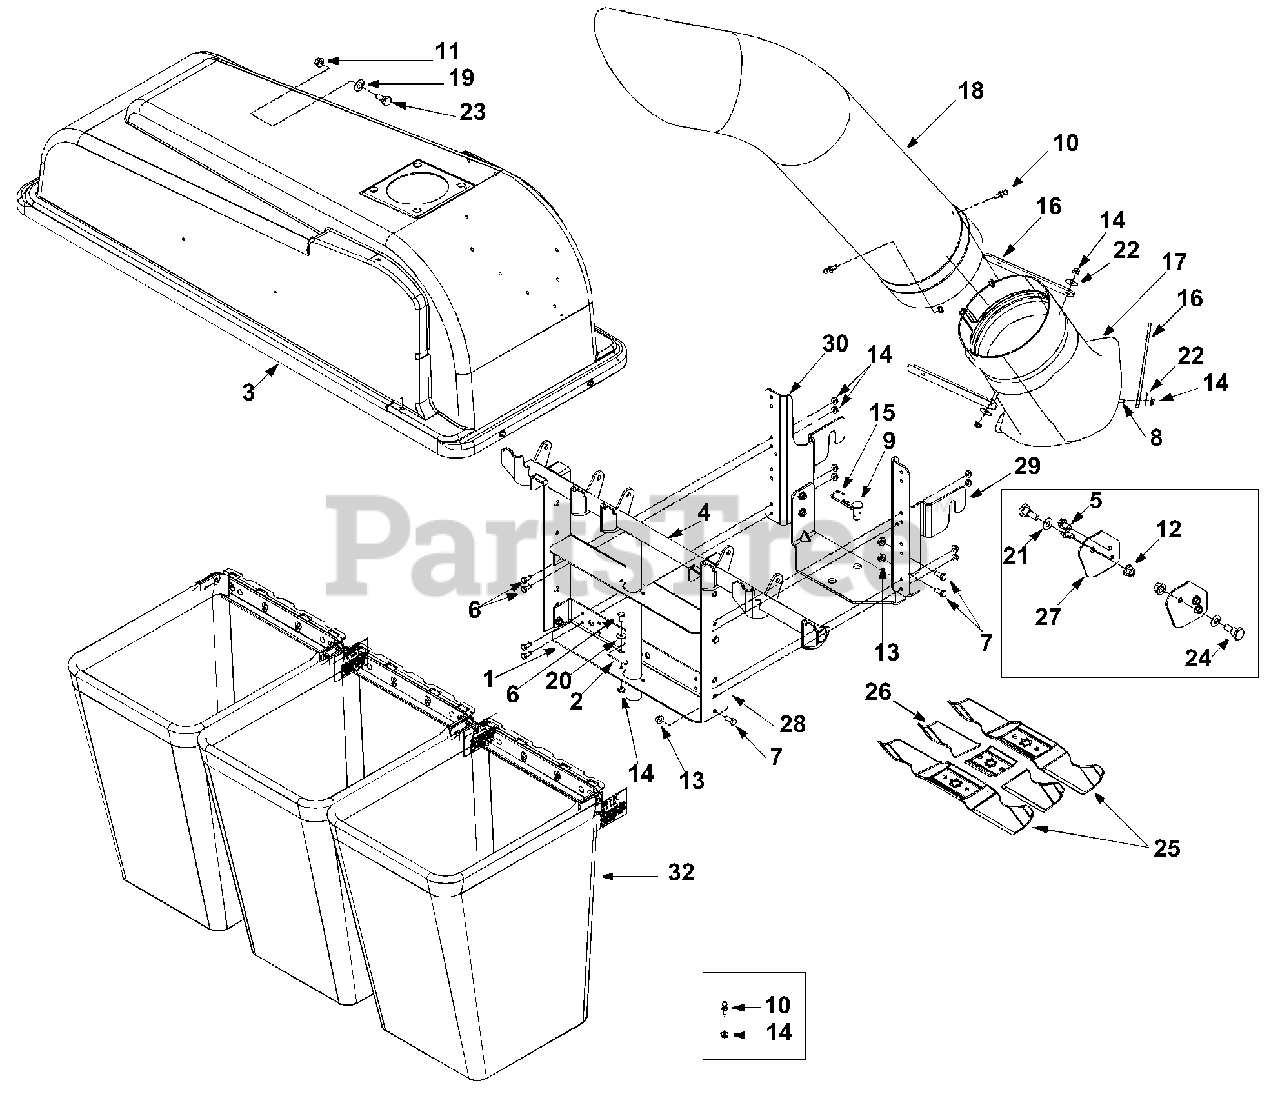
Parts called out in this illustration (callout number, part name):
3	Grass catcher Cover Assembly
6	Hex Screw 1/4-20 x 0.620
7	Hex Screw 5/16-18 x 0.75
8	Hex Screw 1/4-20 x 0.75
9	Clevis Pin
10	Grass catcher Pin
11	Flange Lock Nut 3/8-16
12	Lock Nut 7/16-20
13	Lock Nut 5/16-18
14	Lock Nut 1/4-20
15	Hairpin Clip
16	Chute Strap
17	Discharge Chute Elbow
18	Catcher Tube
19	Bellville Washer
20	Bellville Washer
21	Bell Washer
22	Flat Washer
23	Shoulder Screw
24	Shoulder Screw
25	Blade 16.28"
26	Blade 14.88"
32	Bag Assembly: Triple Bagger
